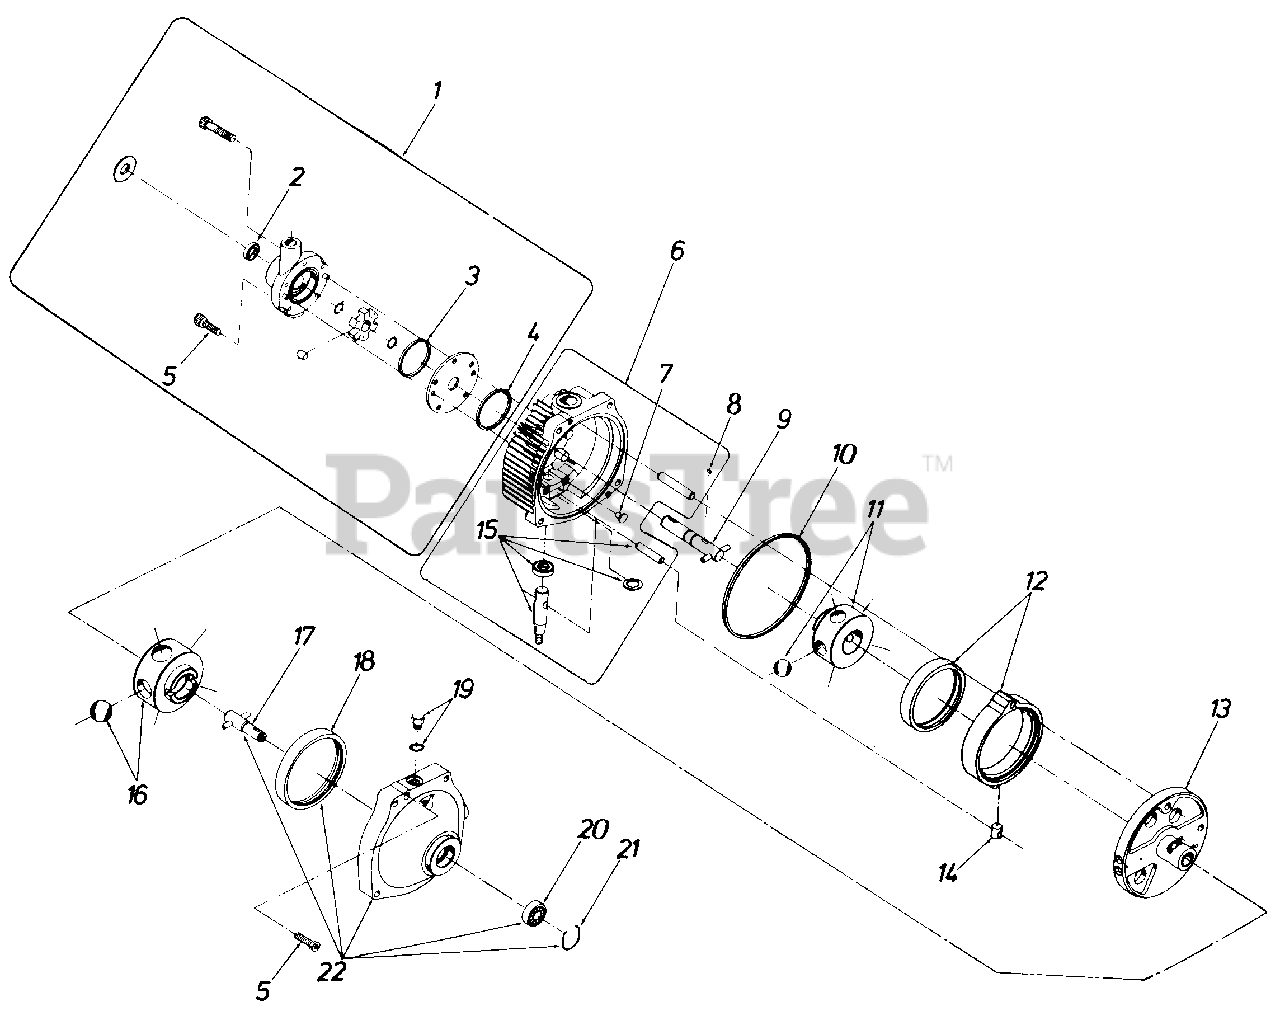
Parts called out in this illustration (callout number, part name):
1	Charge Pump Kit
3	Square Cut Seal Ring .036
4	Square Cut Seal R;ng .038
5	Socket Head Cap Screw 5/16-18 x 1.25" Long
6	Cover Subassembly
8	Drive Pin
9	Input Shaft Subassembly
10	Square Cut Seal Ring .166
11	Pump Rotor-Ball Subassembly
12	Cam Ring Subassembly
13	Pintle Subassembly
14	Cam Ring Insert
15	Control Shaft Kit
16	Motor Rotor-Ball Subassembly
17	Output Shaft Subassembly
18	Motor Race
19	"O"-Ring Plug Subassembly
20	Ball Bearing
21	Retaining Ring
22	Body Subassembly
